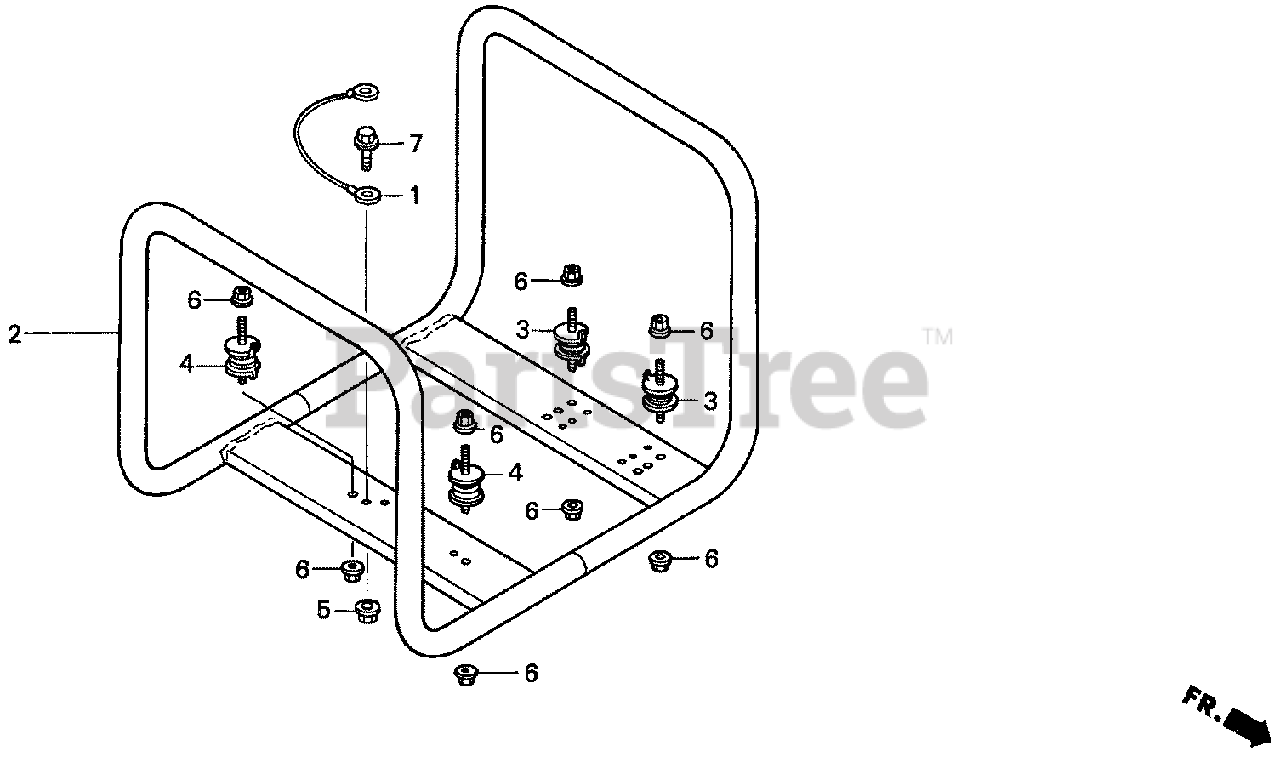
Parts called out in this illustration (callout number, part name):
1	CABLE, GROUND
2	FRAME *NH105* (MAT BLACK)
3	RUBBER (LOWER)
4	RUBBER (LOWER)
5	NUT, FLANGE (6MM)
6	NUT, FLANGE (8MM)
7	BOLT, FLANGE (6X10)
